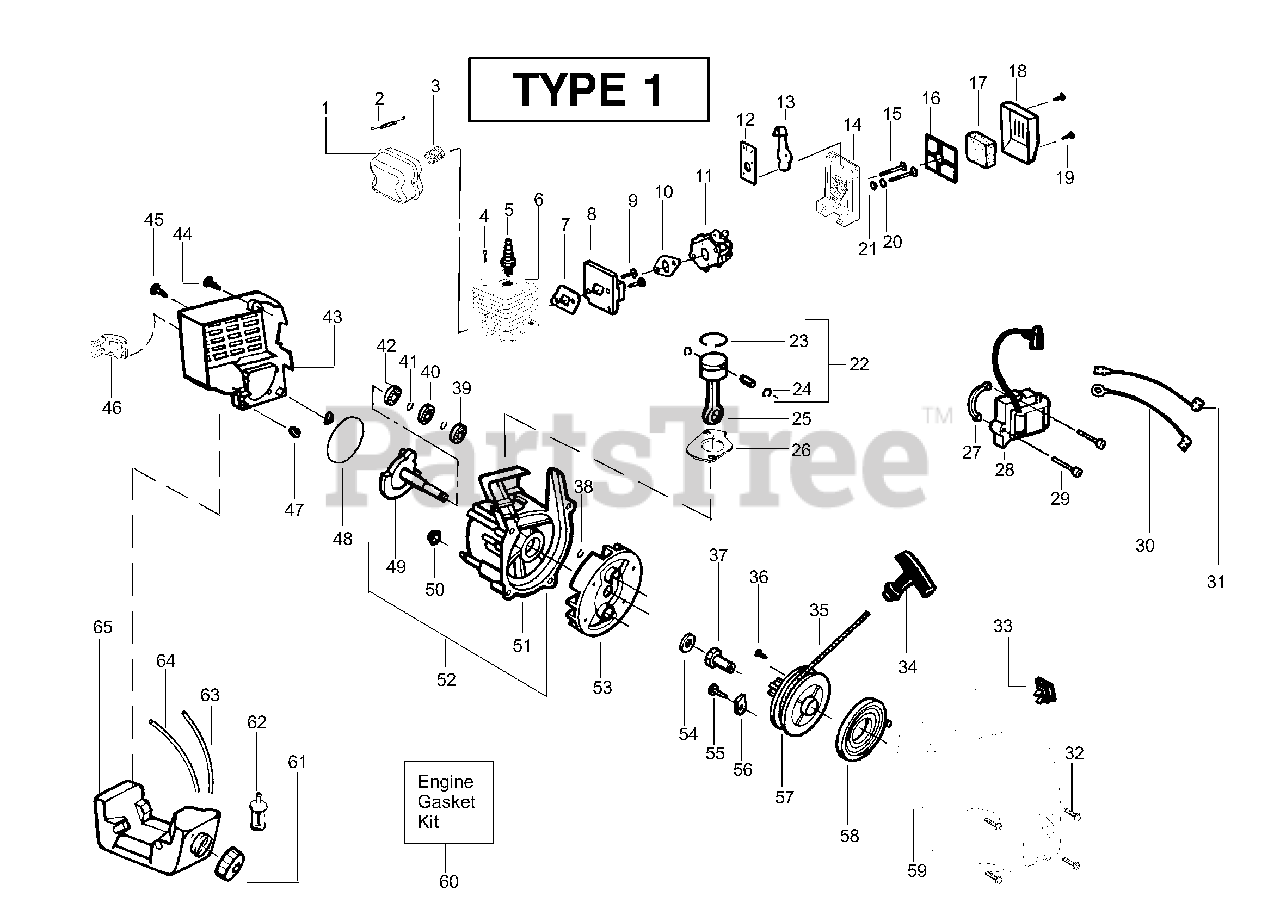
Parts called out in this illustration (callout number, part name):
1	Kit - Muffler
2	Muffler Spring
3	Screen-Spark Arrestor
4	Screw-Cylinder
5	Spark Plug (RCJ 8Y)
6	Kit - Cylinder
7	Gasket-Cylind./Carb.
8	Kit - Carb. Adaptor
10	Gasket-Carb.
11	Kit - Carburetor Ass'y
12	Choke Plate Mounting
13	Choke Shutter
16	Plate - Filter Support
17	Foam-Air Filter
18	Cover-Air Filter
20	Spacer-Choke
22	Kit - Piston
23	Ring-Piston
24	Retainer-Piston Pin
25	Assy-Connecting
26	Gasket-Cylinder
27	Spacer-Module
28	Ignition Module
30	Assy-Ground Wire
31	Assy-Lead Wire
32	Screw
33	Kit - Switch
34	Handle-Starter
35	Kit - Rope
37	Coupling-Drive
38	Retain. Ring-C'shaft
39	Bearing-Outer
40	Seal-C'case
41	Retainer Ring-C'case
42	Bearing-Inner
43	Shroud-Rear
45	Screw
46	Guard-Muffler
47	Isolator-Shroud
48	O-Ring-C'case/Shrd
49	Assy-Crankshaft
50	Isolator-Crankcase
51	Assy-Crankcase
52	Assy-C'case & C'shaft
53	Assy-Flywheel
54	Washer-Flat
56	Retainer-Can
57	Kit-Starter Pulley
58	Spring-Starter
59	Assy. - Fan Housing
60	Kit-Engine Gasket
61	Assy-Fuel Cap
62	Assy-Fuel Pickup
63	Kit-Fuel Line (Small)
64	Kit-Fuel Line (Large)
65	Assy-Fuel Tank
